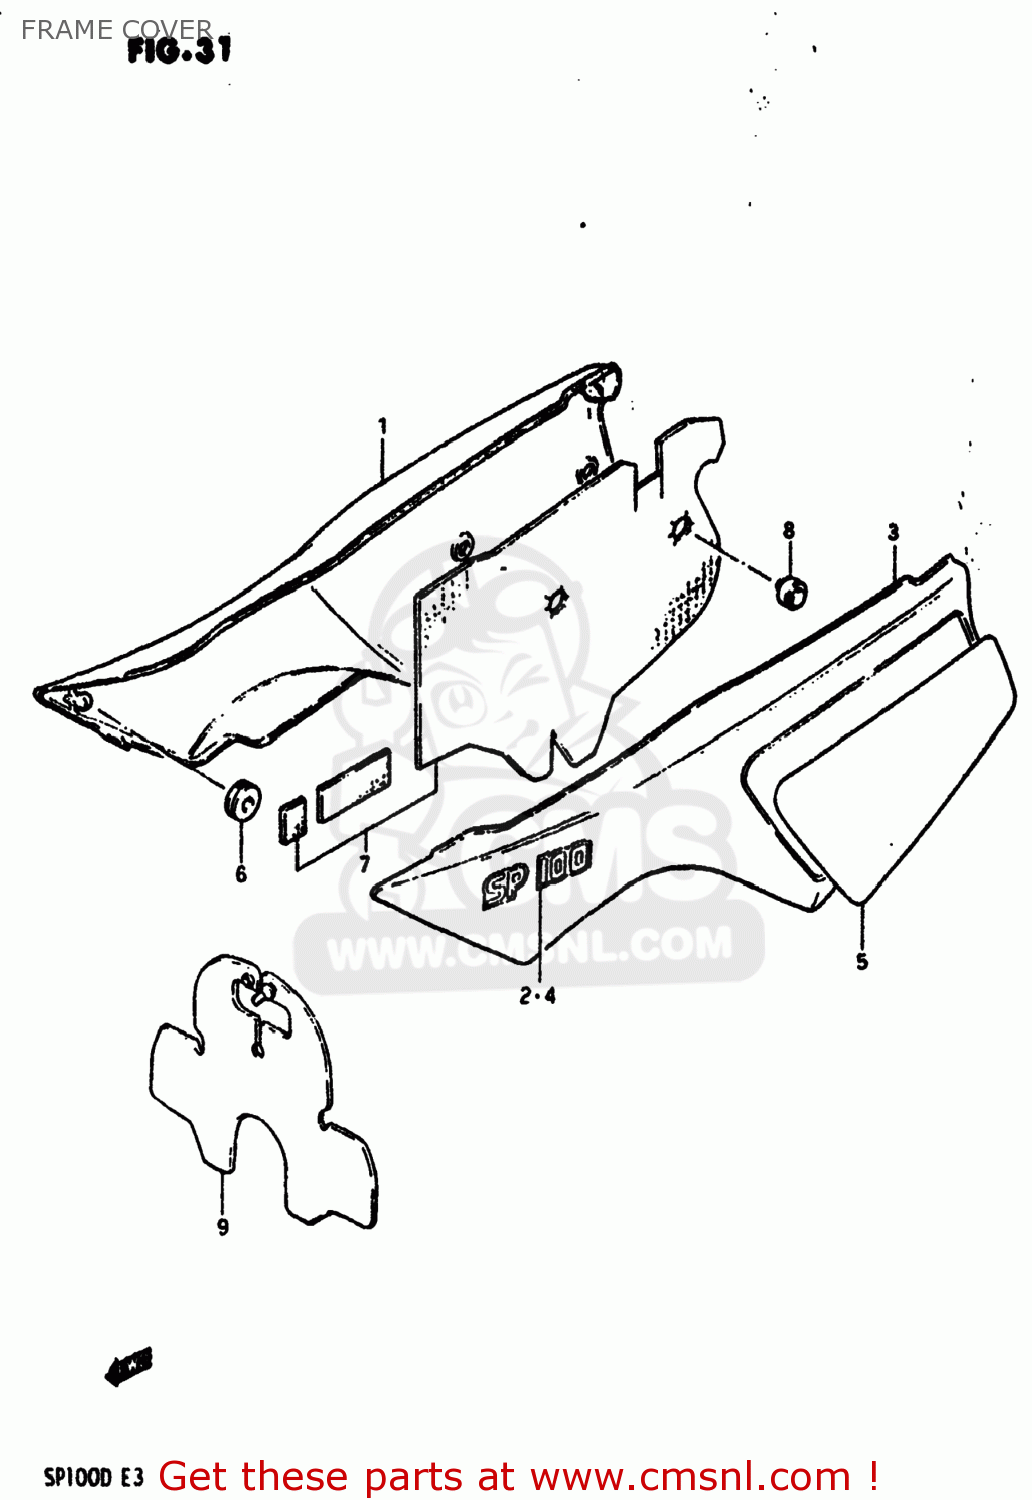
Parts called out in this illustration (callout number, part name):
1	COVER,FRAME,RIGHT
2	EMBLEM
3	COVER,FRAME,LEFT
4	EMBLEM
5	EMBLEM,FRAME COVER
6	CUSHION
7	SHIELD SET,FRAME COVER H
8	CUSHION
9	MUD FLAP,FRONT
